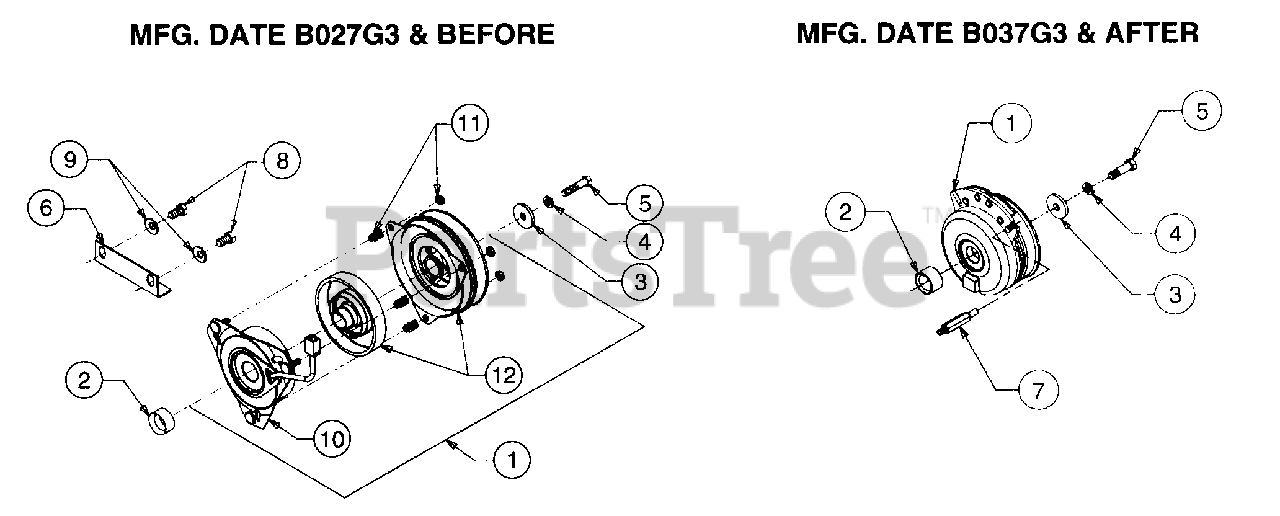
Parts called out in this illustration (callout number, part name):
1	Clutch Assy, PTO CVX Style - Mfg. Date B027G3 & Before
2	Spacer
3	Washer, Flat, .45 x 1.5 x .172
4	Washer, Lock, 3/8
5	Screw, Hex Cap, 3/8-24 x 1.75 GR5 Mfg. Date B027G3 & Before
8	Screw, Hex Cap Mfg. Date B027G3 & Before
9	Washer, Bell, .45 x 1.0 x .062 Mfg. Date B027G3 & Before
10	Field Assy - Mfg. Date B027G3 & Before
11	Clutch Hardware (3 Hex Nuts; 3 Springs) Mfg. Date B027G3 & Before
12	Kit, Armature and Rotor Mfg. Date B027G3 & Before
